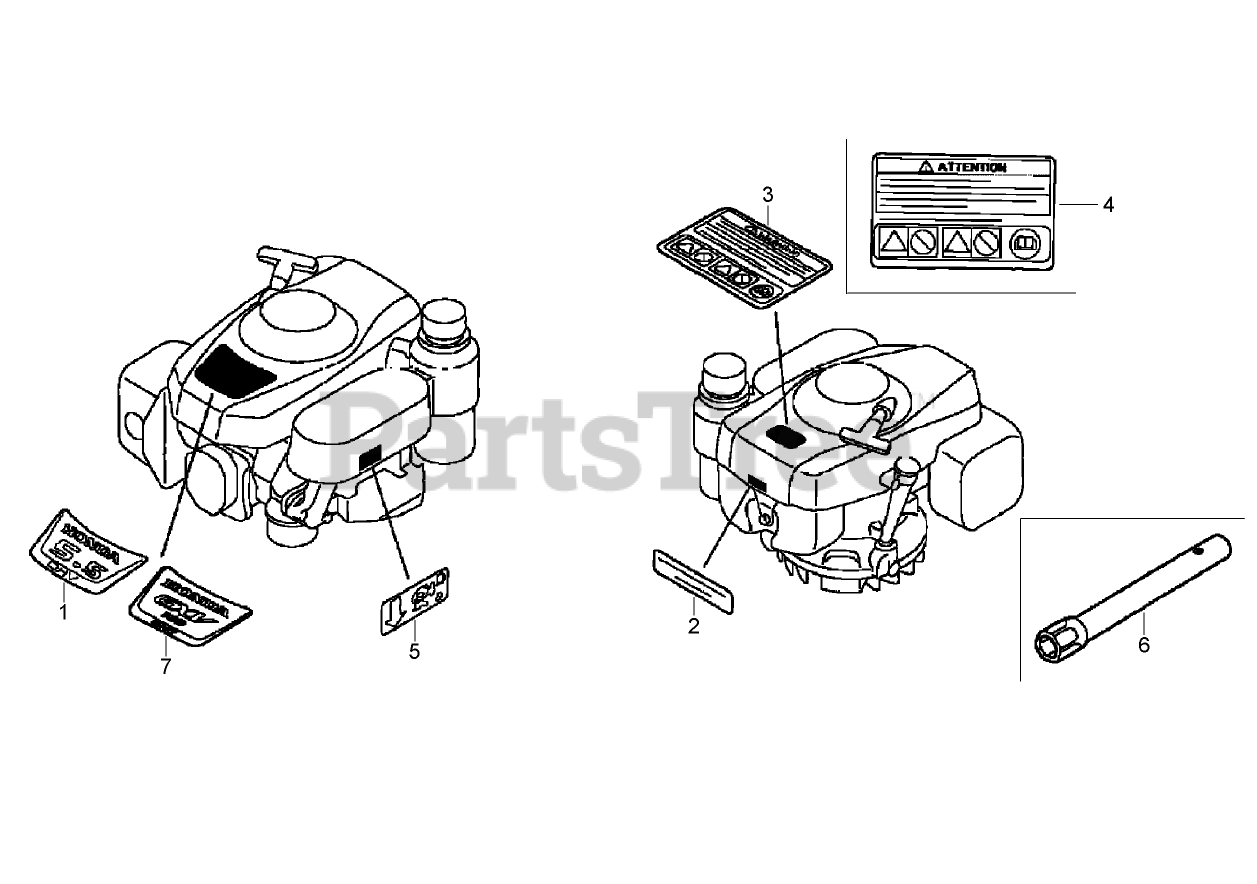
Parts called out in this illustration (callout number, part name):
1	MARK, EMBLEM (SERIAL NUMBERS UP TO 1036455)
2	MARK-MANUFACTURER
3	MARK-CAUTION, OPERATOR (ENGLISH)
3	MARK-CAUTION, OPERATOR (FRENCH)
4	MARK-CAUTION, OPERATOR (PICTOGRAPH)
5	MARK-CAUTION, FUEL PETCOCK
6	Wrench-Box (P21)
7	MARK, EMBLEM (GXV160) (SERIAL NUMBERS FROM 1036456)
